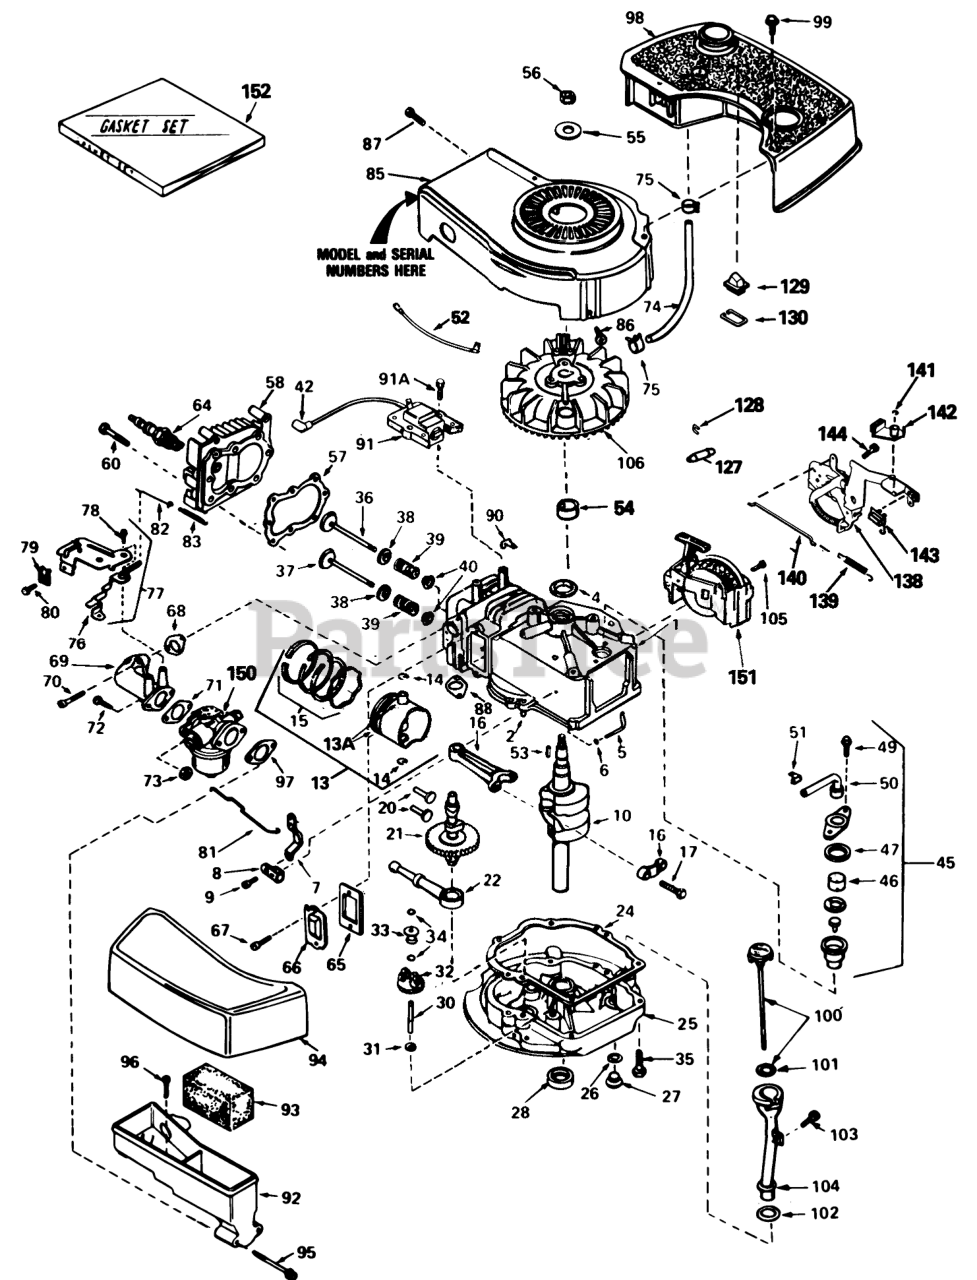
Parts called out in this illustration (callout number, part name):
1	Cylinder Assy. (Inc. #2 & 4)
2	Pin-Dowel
4	Seal-Oil
5	Rod, Governor (Incl. #6)
6	Washer-Flat
7	Governor Lever
8	Clamp-Lever, Governor
9	Screw
10	Crankshaft
13	Piston, Pin & Ring Assy. (Std.) (Incl. #13A, 14 & 15)
13	Piston, Pin & Ring Assy. (.010 oversize) (Incl. #13A, 14 & 15)
13	Piston, Pin & Ring Assy. (.020 oversize) (Incl. #13A. 14 & 15)
13A	Piston & Pin Assy. (Std.) (Inc. #14)
13A	Piston & Pin Assy. (.010 oversize) (Incl. #14)
13A	Piston & Pin Assy. (.020 oversize) (Incl. #14)
14	Ring-Retaining, Piston Pin
15	Ring Set (Std.)
15	Ring Set (.020" OS)
15	Ring Set (.010" OS)
16	Rod Assy., Connecting (Incl. #17)
17	Bolt-Rod, Connecting
20	Lifter-Valve
21	Camshaft(Mech.Comp. Release)
22	Oil Pump ASM
24	Gasket, Mounting
25	Flange Assy., Mounting (Incl. #26 thru 30)
26	Gasket-Oil Drain
27	Plug Oil Drain
28	Seal Oil
30	Shaft-Governor
31	Washer-Flat
32	Gear Assy., Governor (Incl. #31)
33	Spool-Governor
34	Ring-Retaining
35	Screw (1/4-20 x 1-1/4)
36	Valve, Intake (Std.) (Incl. #40)
36	Valve, Intake (1/32" oversize) (Incl. #40)
37	Valve, Exhaust (Std.) (Incl. #40)
37	Valve, Exhaust (1/32" oversize (Incl. #40)
38	Cap-Upper Valve Spring
39	Spring-Valve
40	Cap-Valve, Spring
42	Cover-Spark Plug
45	Breather Assy. (Incl. #46 thru 51)
46	Element-Breather
47	Gasket-Breather
49	Screw (10-24 x 9/16)
50	Tube, Breaker
51	Clip, Breather
52	Ground Wire
53	Key-Flywheel
55	Washer-Belleville
56	Nut-Flywheel
57	63573 GIL 42 SNWTHW
58	Head-Cylinder
60	Screw (5/16-18x1-1/2)
64	Plug, Spark (J17LM or equiv.)
64	Plug, Spark (Champion RCJ-8)
65	Gasket-Breather
66	Cover-Valve
68	Gasket-Intake
69	Pipe, Intake (Incl. #68)
70	Screw (1/4-20 x 1)
71	Gasket-Carburetor
72	Screw (1/4-28 x 7/8)
73	Nut and Lock Washer (1/4-28)
74	Line-Fuel
75	Clamp-Line, Fuel
76	Lever Control
77	Control Assy., Speed (Incl. #76 & 78)
78	Screw, Hex Washer Hd Shoulder Self-Tap
79	Conduit
80	Screw (10-32 x 3/8)
81	Link-Throttle
82	Link Governor Spring
83	Spring Governor
85	Housing-Blower
86	Screw (1/4-20x19/32)
87	Screw (10-24 x 9/16)
88	Gasket Exhaust
90	Clip-Wire
91	Lamination & Coil Assy.(Solid State) (Incl. #42)
91A	Screw
92	Body Air Cleaner
93	Filer, Air
94	Cove, Air Cleaner
95	Screw Fil Hd.
96	Screw, Hex Hd.
97	Gasket-Air Cleaner
98	Tank, Fuel
99	Screw (10-32 x 35/64)
100	Dipstick, Oil (Incl. #101)
103	Screw (10-32 x 1/2)
104	Tube-Oil Fill
105	Screw (1/2-20x5/8)
106	Flywheel
127	Coupling, Starter Rope
128	Staple, Rope Retainer (Strip of 25 Pieces)
129	Pulley Assy., Starter
130	Retainer, Pulley
138	Bracket Assy.
139	Spring-Extension
140	Link-Control
141	Ring-Retaining
142	Lever-Brake
143	Terminal
144	Screw-Hex. Hd.
150	Carburetor (Incl. #71)
151	Starter, Sidemount rewind
152	Gasket Set (Incl. Items Marked )
